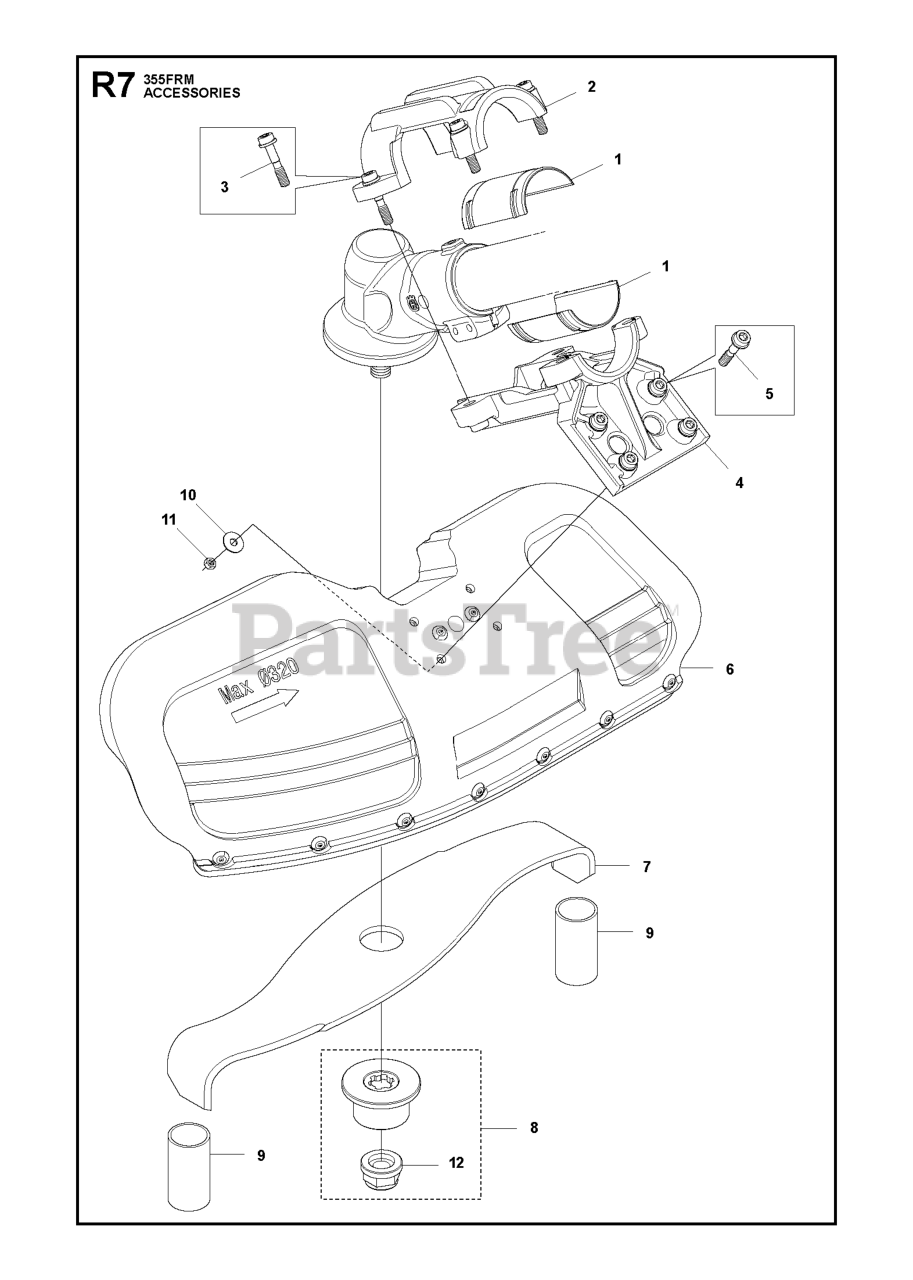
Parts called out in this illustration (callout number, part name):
2	CLAMP
3	SCREW IHSCFMO
4	BRACKET
5	SCREW IHSCFMO
6	SPRAY GUARD ASSY
9	TRANSPORT GUARD
11	LOCKNUT M5
